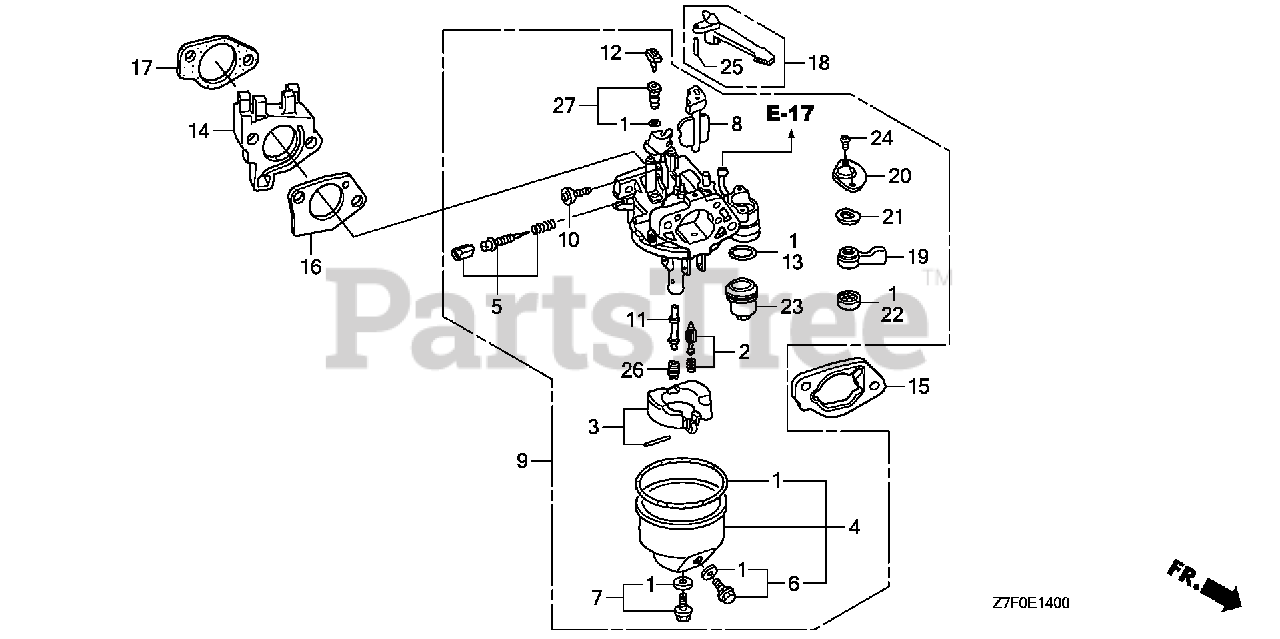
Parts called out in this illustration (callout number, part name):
1	GASKET SET (INCLUDES 16173-001-004)
2	VALVE SET, FLOAT
4	CHAMBER SET, FLOAT
5	SCREW SET, PILOT
6	SCREW SET, DRAIN
7	SCREW SET
9	CARBURETOR ASSY. (BE85T A/B)
10	SCREW, THROTTLE STOP
11	NOZZLE, MAIN
12	COLLAR, SETTING
13	GASKET, FUEL STRAINER CUP
14	INSULATOR, CARBURETOR
15	SPACER, CARBURETOR
16	GASKET, CARBURETOR
17	GASKET, INSULATOR
18	LEVER, CHOKE (STD)
19	LEVER, PETCOCK
20	PLATE, LEVER SETTING
21	SPRING, PETCOCK LEVER
22	GASKET, PETCOCK
23	CUP, FUEL STRAINER
24	SCREW, PAN (3X6)
25	PIN, SPRING (2X12)
26	JET, MAIN (#88)
26	JET, MAIN (#90)
26	JET, MAIN (#92)
27	JET SET, PILOT (#45)
